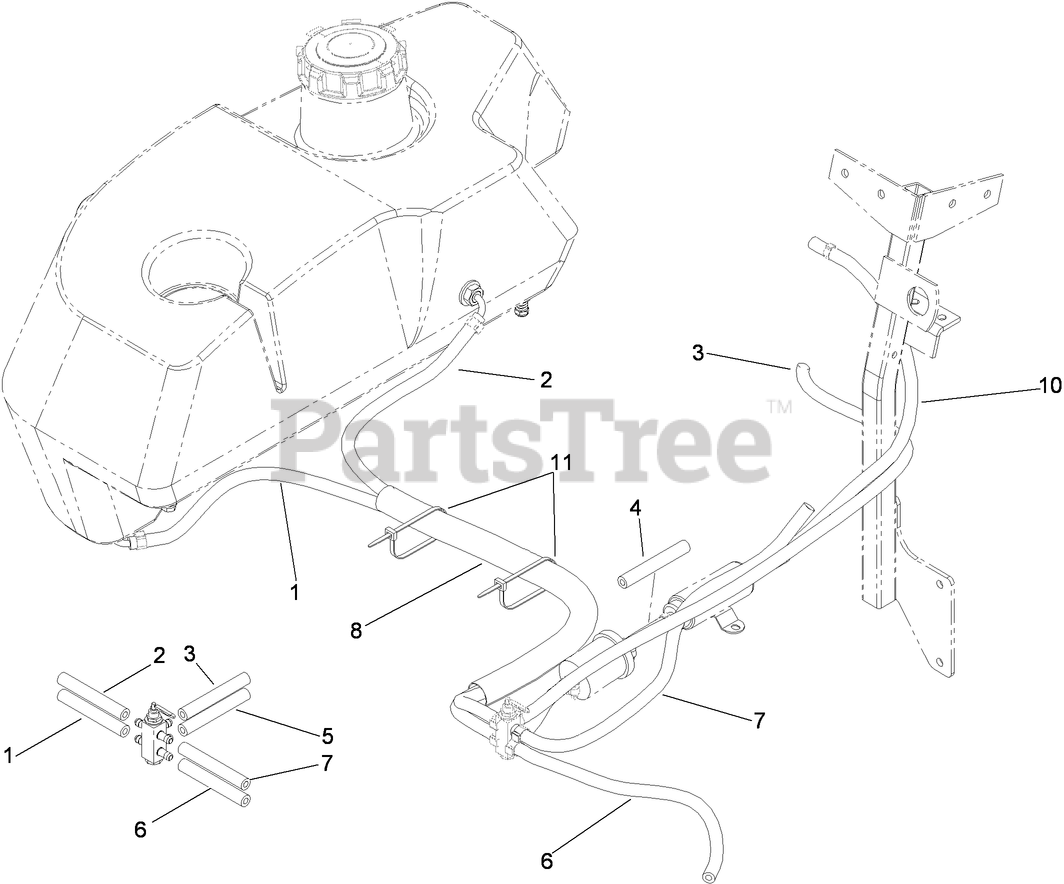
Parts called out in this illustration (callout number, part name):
1	HOSE-FUEL
2	HOSE-FUEL
3	HOSE-FUEL
4	HOSE-FUEL
5	HOSE-FUEL
6	HOSE-FUEL
7	HOSE-FUEL
8	SLEEVE-FABRIC
10	HOSE-FUEL
11	TIE-CABLE
